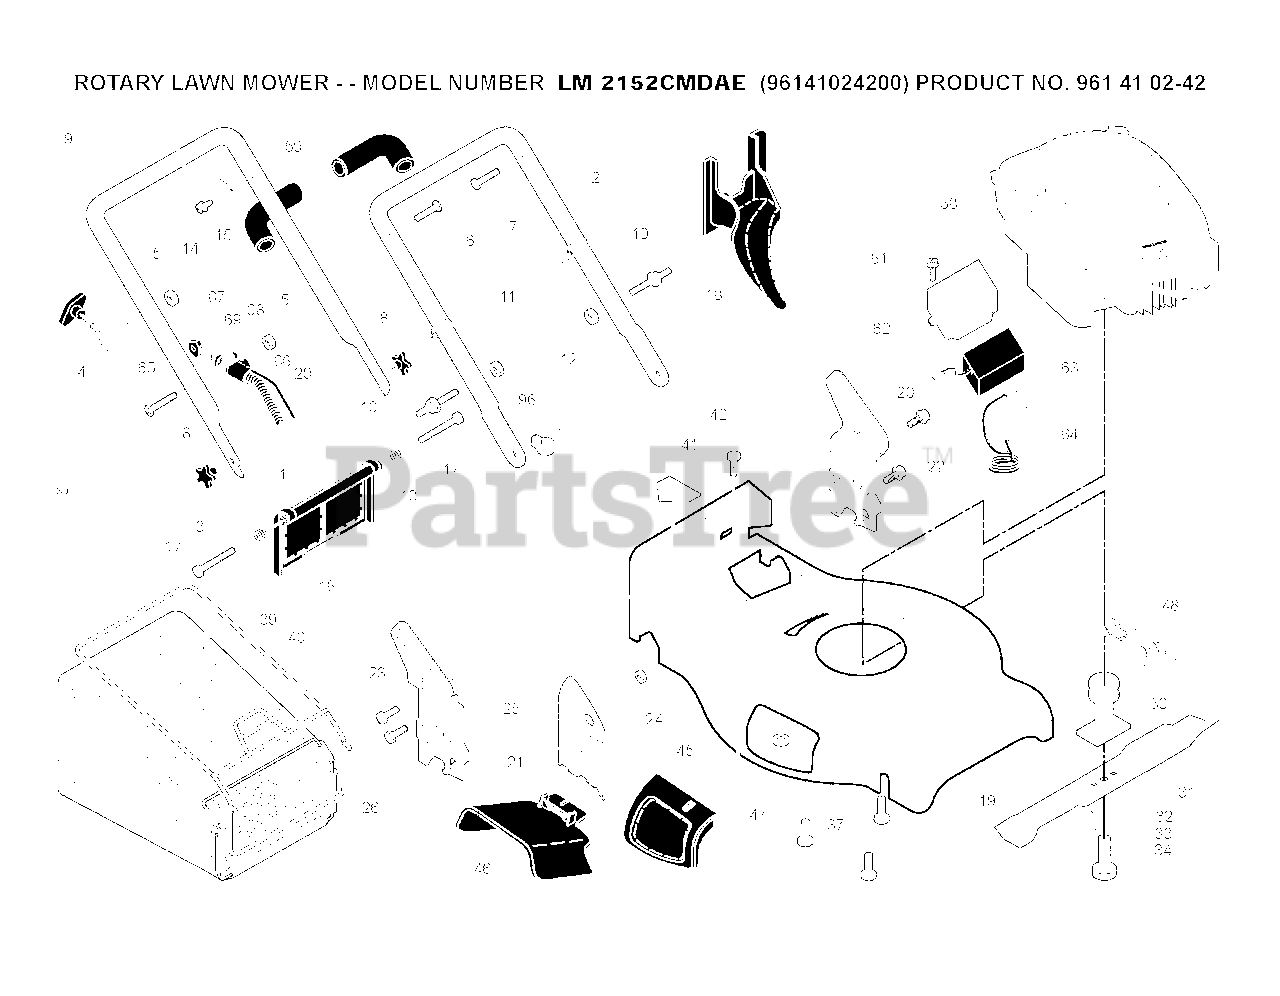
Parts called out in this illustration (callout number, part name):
2	HANDLE LOWER
3	SPRING.RH.REAR.DOOR.21.RWGD
4	GUIDE.ROPE.STD.BLK.ZIN
5	NUT
6	TIE GUIDE
7	BOLT, HANDLE 5/16-18X1.75
8	KNOB, DEFLECTOR
11	NUT, LOCK 5/16-18
12	HAIRPIN COTTER
13	SPRING.LH.REAR.DOOR.21.RWGD
15	BRACKET.UPSTOP.RT
16	REAR DOOR ASSEMBLY
18	PLUG.MULCHER.RGD.21.
20	BRKT.ASM HNDL
21	BRKT.ASM.HNDL
22	BOLT.HEX.HD.WASHER.5/16-18X.75
23	BOLT, HEX HEAD 5/16-18
24	NUT.71038.31-18.HEX.NYLOCK
25	CLIPPING DEFLECTOR
29	CABLE.MZR.47.75.SNAP-IN.PU.L
30	ADAPTER.BLADE/PULLEY.25M
31	BLADE.21.PUSH
32	WASHER,HARDEN
33	LOCKWASHER
34	SCREW, HEX HD 3/8-24 X 1-3/8
37	BOLT 3/8-16X1-1/8
40	FRAME.GBAG.21.RWGD.SC
41	DECAL.INTERNATIONL.CUTFINGER
48	BRACKET.ENG/BELTKEEPER.BZP
59	GRIP.HANDLE.FOAM.WIDE.(1 SIDE)
63	BATTERY.AMP.CONNECTOR
65	SCREW.(COMBINATION CONTROL)
67	KEY.MOLDED
68	HOUSING.WIRING.HARNESS
69	NUT.CAP.SNAP-ON.KEY START
96	CLIP.CABLE.BLK
